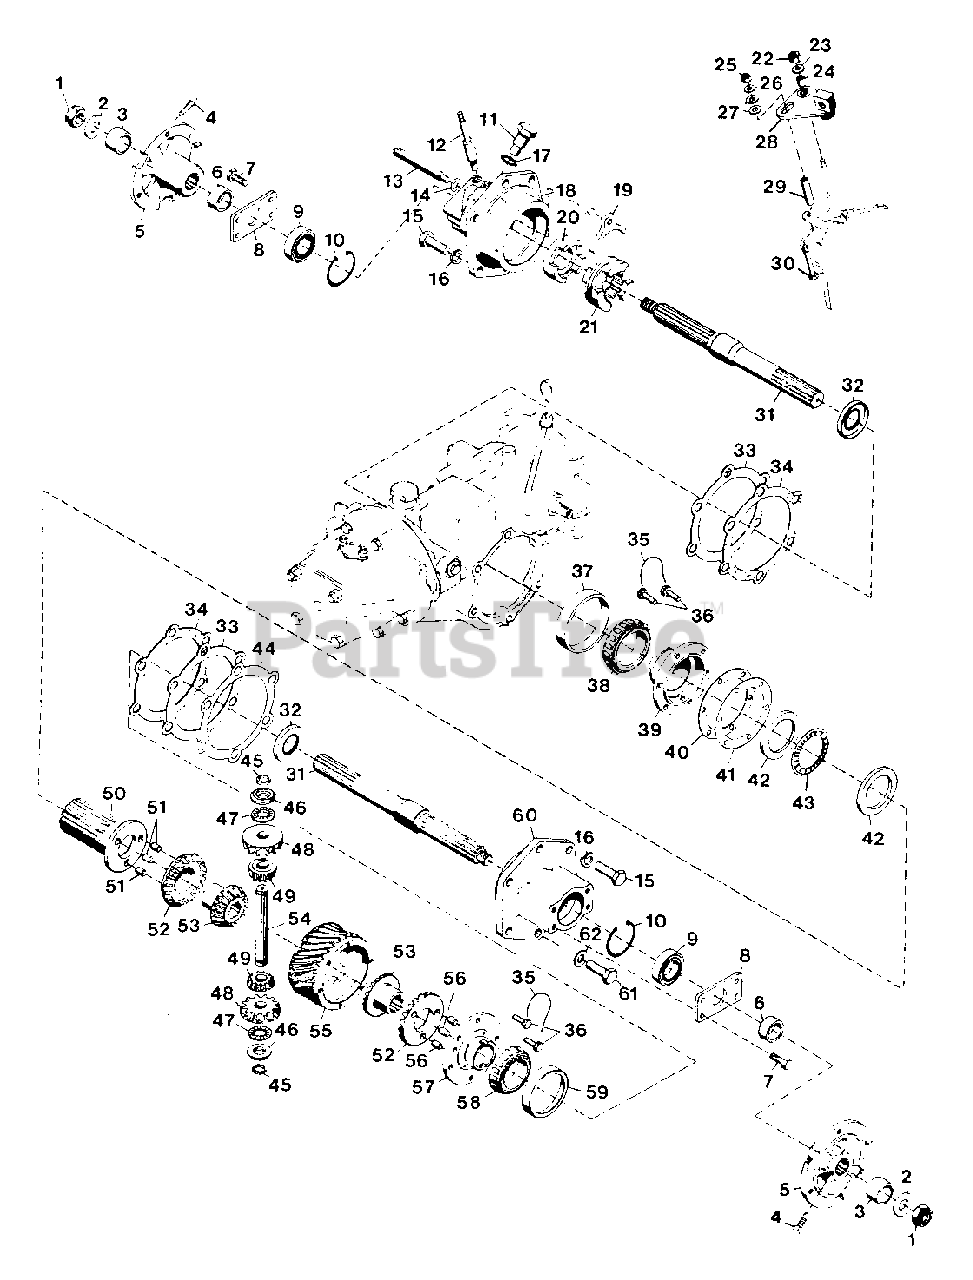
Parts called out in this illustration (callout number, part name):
1	Nut, Hex 3/4-10 Light Thin
2	Washer, Flat .812x1.469x.134
3	Spacer
4	Screw, Set 7/16-14x1.0 SQHCP
5	Hub, Wheel
6	Spacer
7	Bolt, Hex 3/8-16x.750
8	Plate, End
9	Brg, Ball 1000x2.000x.562
10	Ring, Retaining 2.000 Bore
11	Bolt, Stationary Clutch
12	Pivot, Stationary
13	Pin, Clutch Sliding
14	O-Ring .438x.625x.094
15	Bolt, Hex 1/2-13x1.00
16	Washer, Lock 1/2 Reg.
17	Washer, Oil Strainer Nut
18	Housing, Axle 2-Speed
19	Yoke, Shifting
20	Clutch, Stationary
21	Clutch, Shifting
22	Nut, Lock 5/16-18
23	Washer, Flat .344x.688x.065
24	Bushing, Nylon .375x.503x.875
25	Nut, Lock 1/4-20
26	Washer, Flat .281x.625x.065
27	Washer, Flat .406x.812x.065
28	Weldment, Arm Shifter
29	Bushing
30	Bolt, 1/4-20x2.25 Gr. 8 PHD
31	Axle, Straight
32	Seal, Oil 1.188x2.000x.250
33	Shim, Axle Housing .020
34	Gasket, Axle Housing
36	Bolt, Special 5/16-18
37	Cup, Roller Bearing
38	Cone, Roller Bearing
39	Housing, Clutch
40	Shim, Worm Gear .020
41	Shim, Worm Gear .005
42	Race, Thrust 2.00x2.740x.031
43	Brg, Needle Thrust .060
44	Shim, Axle Housing .005
45	Ring, Retaining .750 Shaft
46	Spacer, .7650.245x.200
47	Brg, Needle Thst .752x1.24x.078
48	Gear, Diff. Shifting Bevel
49	Gear, Spider Bevel
50	Shifter, Splined Pinned
51	Pin, Dowel .375x.375
52	Gear, Pinned Bevel
53	Gear, Differential Bevel
54	Pin, Spider
55	Gear, Worm 8 Start
55	Gear, Worm 6 Start
56	Pin, Dowel .375x.500
57	Housing, Pinned
58	Cone, Roller Bearing
59	Cup, Roller Bearing
60	Housing, Axle
61	Bolt,Hex 1/2-13x1 Nylon Ins.
62	Seal, Oil Drain
